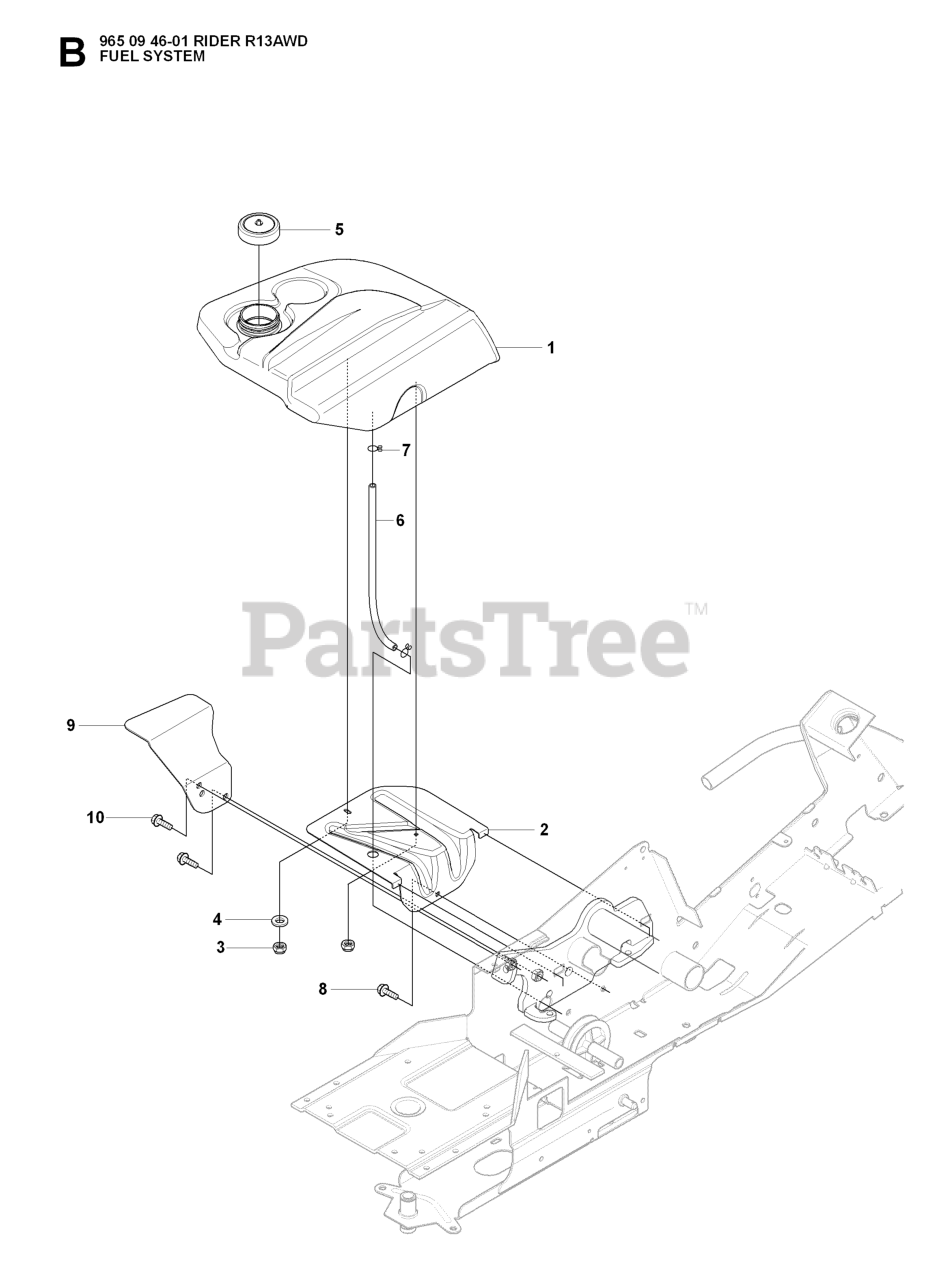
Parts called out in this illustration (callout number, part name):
3	LOCKNUT M6
4	WASHER
10	Screw M10x25
